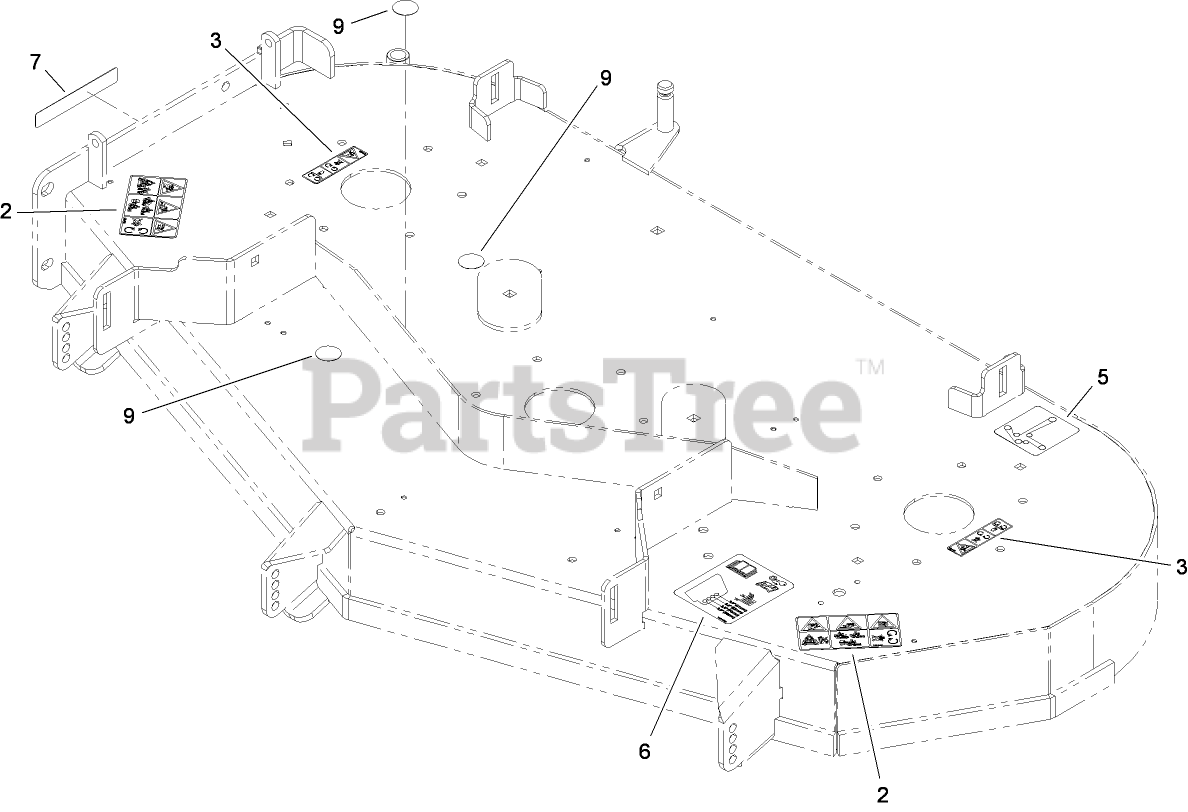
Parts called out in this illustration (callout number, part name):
2	DECAL-DANGER
3	DECAL-WARNING, BELT SHIELD
5	DECAL-BELT ROUTING
6	DECAL-ROLLER, ANTI-SCALP
7	DECAL-DANGER
9	DECAL-COVER, HOLE
